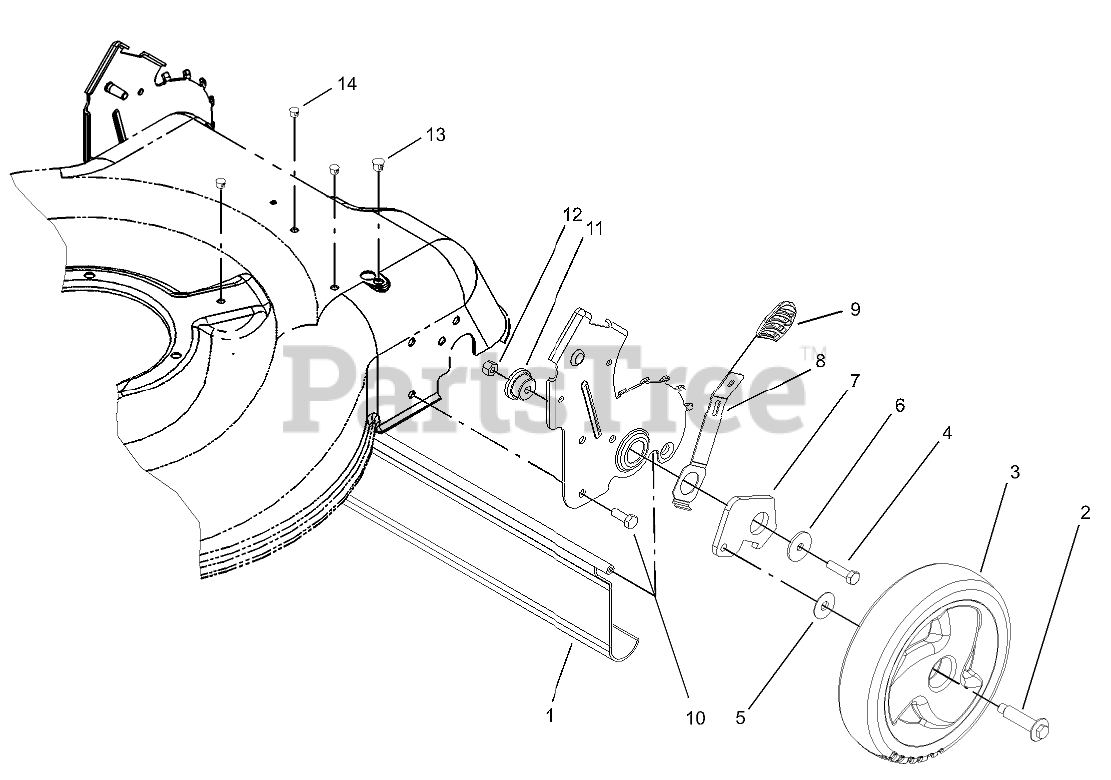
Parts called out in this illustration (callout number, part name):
1	Shield-Trailing
2	BOLT-SHOULDER
3	WHEEL ASM (59505)
4	SCREW-HH
5	WASHER
6	Washer-Flat
7	Arm-Pivot, Rear (LH)
8	Arm-Spring
9	Knob-Lever, HOC
10	SCREW-HH
11	Bushing-Mount, HOC
12	NUT-LOCK, NI
13	Plug-Dome
14	Plug-Dome
